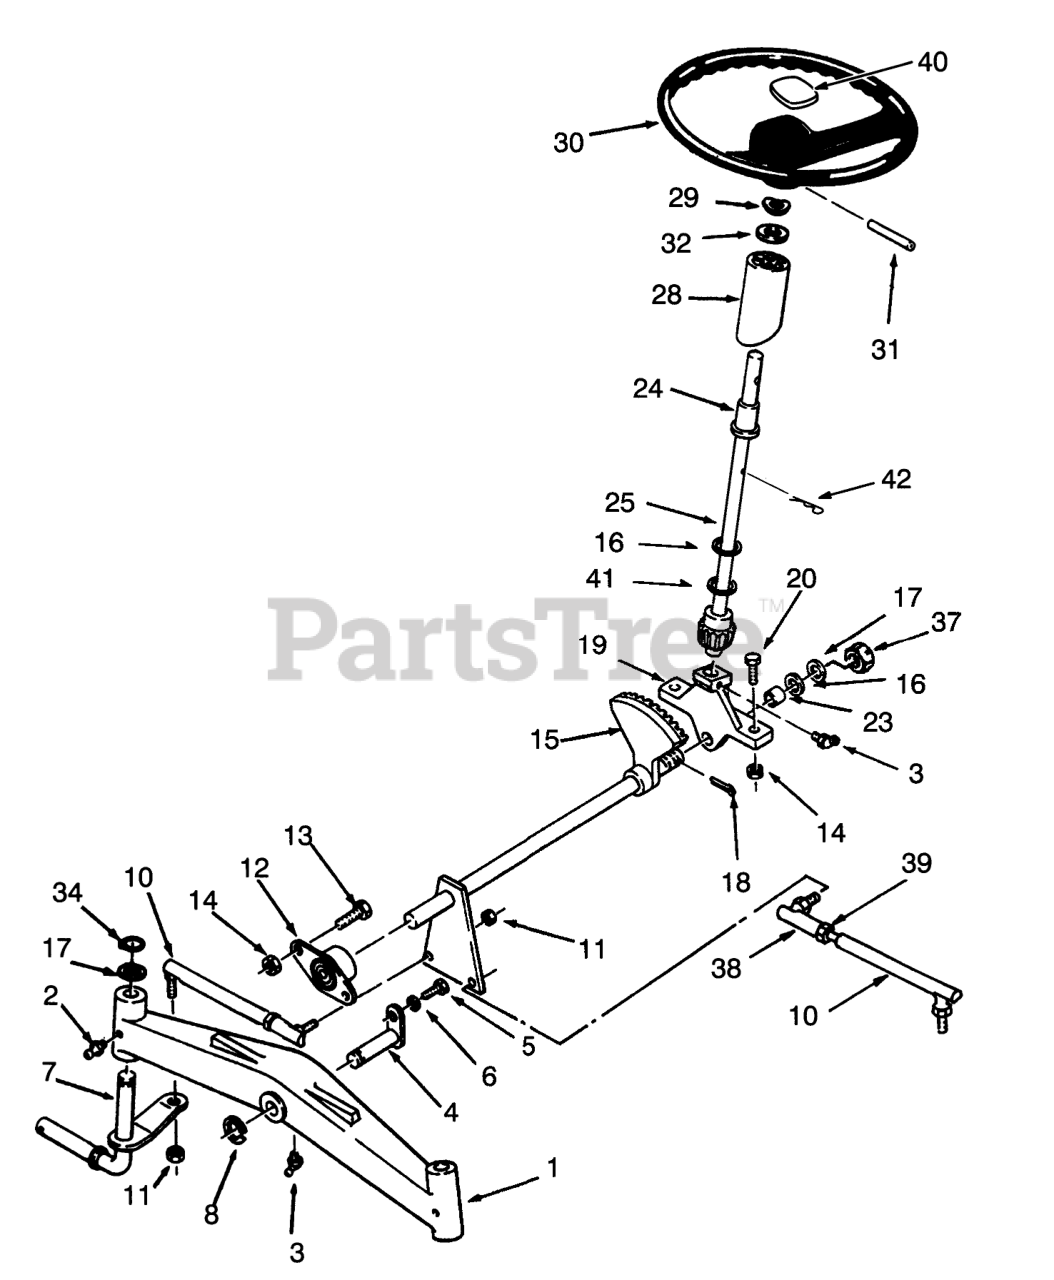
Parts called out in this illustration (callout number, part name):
1	AXLE-FRONT
2	FITTING-GREASE
3	FITTING-GREASE
4	PIN AND PLATE ASM
5	SCREW-HH
6	WASHER-LOCK
7	RH SPINDLE WA
8	E-RING
10	Tie Rod (Incl. Ref. #38 & 39)
11	Nut
12	BEARING-FLANGED
13	SCREW-HH
14	NUT-LOCK, NI
15	Shaft
16	WASHER-SHIM
17	WASHER
18	PIN-COTTER
19	Support-Steering
20	SCREW-HH
23	BEARING-BRONZE
24	BEARING-FLANGED
25	STEERING SHAFT ASM
28	TUBE-STEERING
29	WASHER-BOWED
30	Steering Wheel (Incl. Ref. #40)
31	PIN-ROLL
32	WASHER-FLAT
34	RING-RETAINING
37	NUT-HEX, SLOTTED
38	BALL-JOINT
39	NUT-6
40	STRG-WHL INSERT TORO
41	O-RING
42	PIN-COTTER
